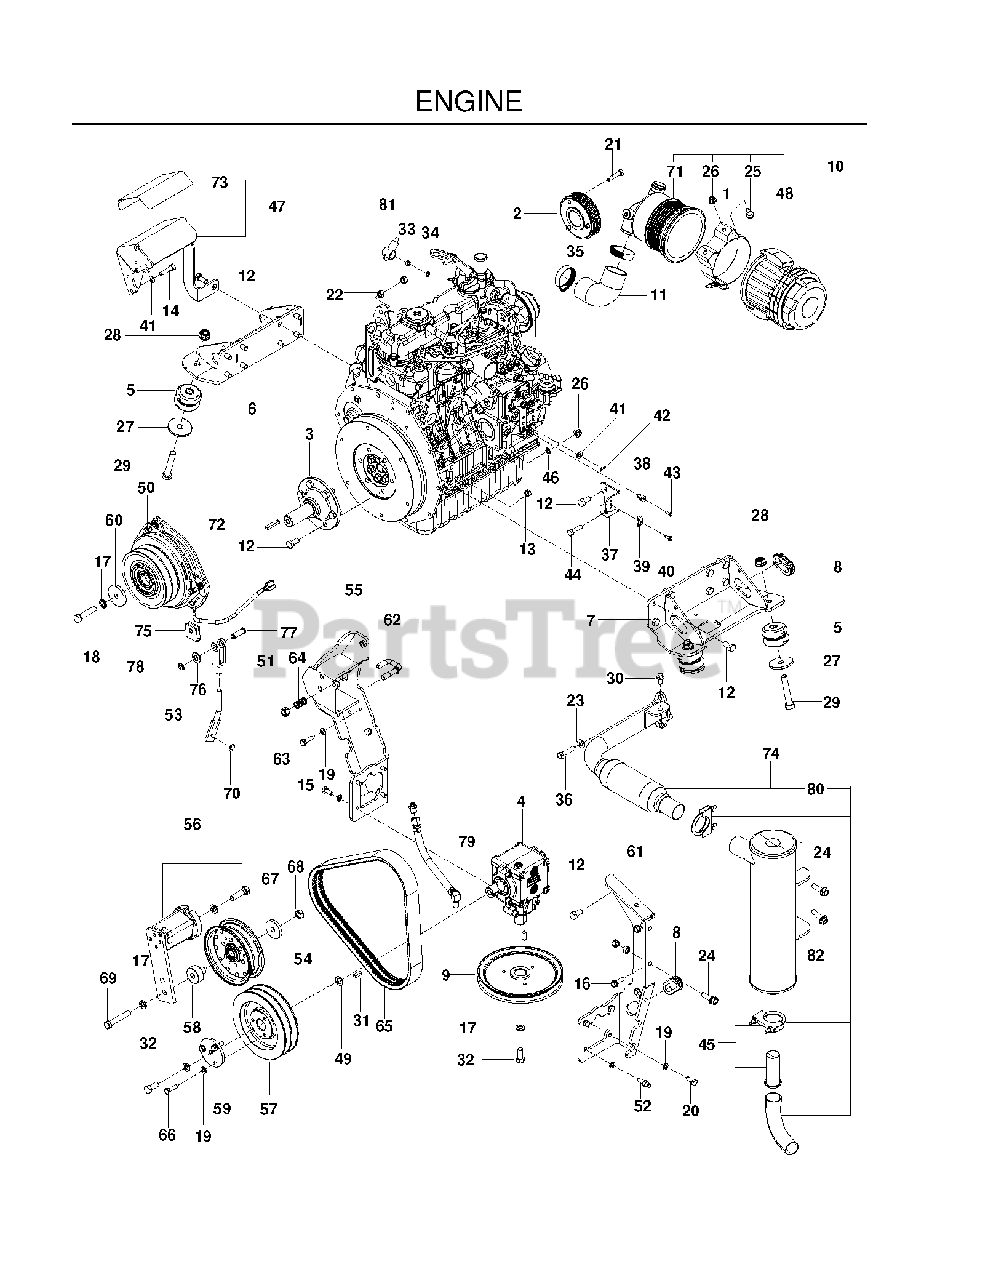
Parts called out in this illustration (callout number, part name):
1	Mounting Bracket
2	Crank Pulley
3	SHAFT, PILOT
4	GEAR BOX, 90 DEGREE
5	ISOLATOR, ENGINE
6	MOUNT, MOTOR, LT - BLK
7	MOUNT, MOTOR, RT - BLK
9	PULLEY, DRIVE, DECK
10	AIR FILTER ASSY - NON-TURBO
11	HOSE, AIR INTAKE
12	HCS M10-1.25 X 20 GR 8.8 ZD
13	NUT 5/16C CENTERLOCK
14	HTB M8-1.125 X 25MM
15	M8X1.25X25 HHB GR8.8
16	5/16-18X1 TAP SCREW
17	WASHER 7/16 LOCK
18	HCS 7/16-20 X 2 G8 ZN
19	WASHER 5/16 LOCK
20	SCREW 5/16C X 1 HEX CAP
21	HCS MB 1.25 X 35 GR 8.8 ZD
22	NUT 3/8C CENTERBLOCK
23	WASHER 3/8 SAE FLAT
24	HHFS 3/8-16 X 1.25 GD 5
25	BOLT 5/16-18 X 3/4
26	5/16-18 NYLOC FLANGE NUT
27	WASHER, HEAVY
28	NUT, 1/2-13 HEX FLG NYLOC ZD
29	HCS 1/2C X 2 3/4
30	SCREW M8X1.25X16 HHB GR 8.8
31	KEY 1/4 SQ X 3/4
32	SCREW 7/16-20 X 1 HHB GR5
33	NUT M6 X 1.0 HEX
34	WASHER 1/4 INT TOOTH
36	HCS 3/8C X 1 1/2
37	Throttle Bracket
38	SWIVEL, THROTTLE
39	Cable Clamp
40	SCREW #10 X 1/2 SELF TAPPING
41	FLAT WASHER 5/16 SAE
42	COTTER PIN 3/32 X 1/2
43	HCS #10-24 X 1/2
44	HCS 5/16C X 1 1/4
45	KIT.SPARK.ARRESTER
46	WASHER 5/16 EXT STAR
47	Shield, Heat
48	PRECLEANER ASM
49	WASHER .515 X .874 X .031
50	CLUTCH, OGURA, DIESEL
51	YOKE, CLEVIS
52	PIN, PIVOT
53	LINKAGE, ANTI-ROTATION
54	IDLER PULLEY
55	MOUNT, GEAR BOX, BLK
56	TENSIONER, LOVEJOY, SE27
57	PULLEY, GEAR BOX
58	MOUNT, IDLER
59	PLATE, PULLEY
60	BLADE WASHER
61	MOUNT, GEAR BOX, BLK
62	PIN, DETENT
63	NUT 7/16C CENTERLOCK
64	SPRING, COMPRESSION
65	BELT, CLUTCH
66	HCS 5/16C X 1
67	SPINDLE WASHER
68	NUT, 7/16-20 HEX NYLOC ZC
69	HCS 7/16-20 X 2-3/4
70	E RING 3/8"
71	BODY - 90 DEG
72	KEY 1/4 SQ X 1-1/2
73	SHIELD, HEAT BARRIER
74	MUFFLER.DIESEL.KUBOTA
75	SPACER, RUBBER
76	WASH 1/2 X 1 SPRG STL & NEOP
77	PIN, 7/16 CLEVIS
78	RING, E, 7/16
79	HOSE, VENT
80	PIPE, MANIFOLD, DIESEL
81	TERMINAL COVER-SM
82	MUFFLER, DIESEL
